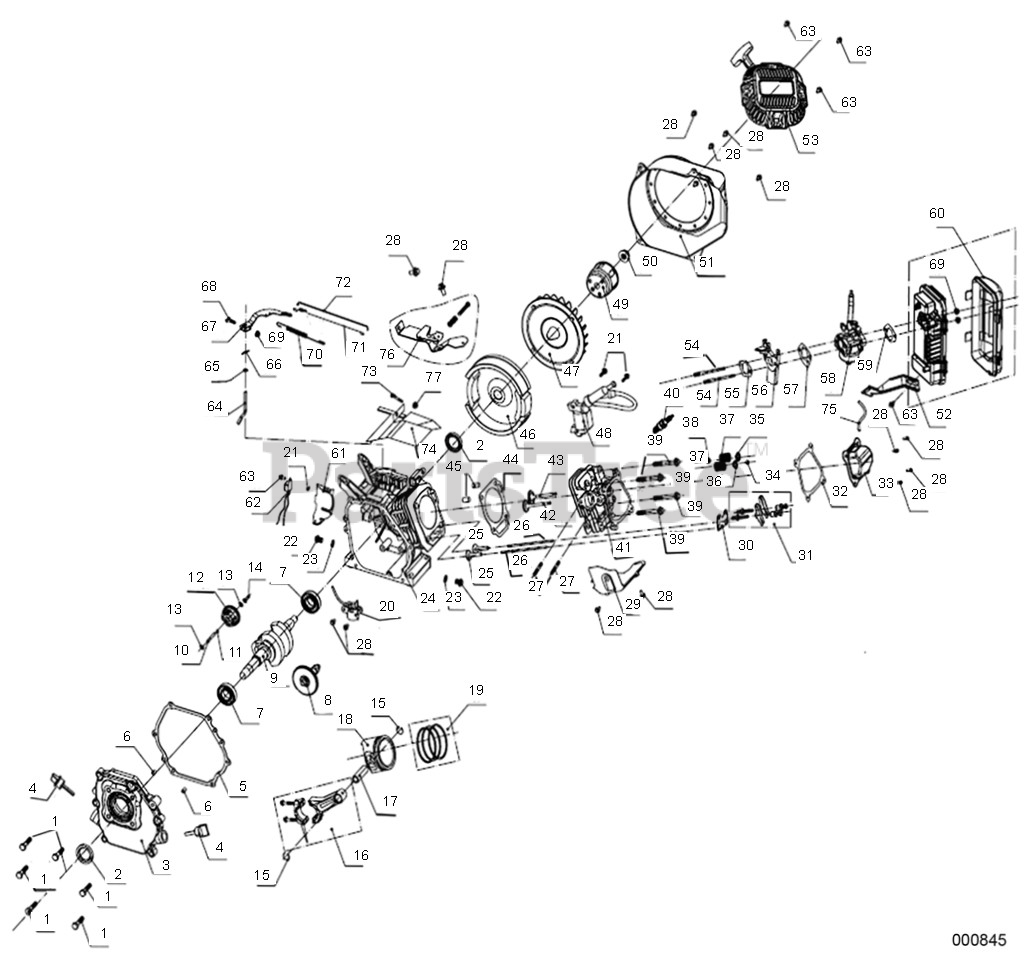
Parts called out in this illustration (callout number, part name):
1	BOLT (M8X33.5)
2	OIL SEAL (B2541)
3	CRANKCASE COVER
4	OIL DIPSTICK ASSEMBLY
5	CRANKCASE GASKET
6	DOWEL PIN (M8X14)
7	BEARING (6205)
8	CAMSHAFT ASSEMBLY
9	CRANKSHAFT ASSEMBLY
10	REGULATING SHAFT
11	SNAP RING
12	SPEED GOVERNING GEAR
13	GOVERNOR ARM SHAFT WASHER
14	GOVERNOR SPOOL
15	PISTON PIN CIRCLIP
16	CONNECTING ROD ASSEMBLY
17	PISTON PIN
19	PISTON RING SET
20	LOW OIL SENSOR
21	BOLT (M6X22)
22	OIL DRAIN BOLT (M10X15)
23	OIL DRAIN BOLT GASKET
24	CRANKCASE
25	VALVE TAPPET
27	STUD (M8X34)
28	BOLT (M6X12)
30	PUSH GUIDE ASSEMBLY
31	VALVE ROCKER ASSEMBLY
32	CYLINDER HEAD COVER GASKET
33	CYLINDER HEAD COVER
35	INTAKE SPRING SEAT
36	EXHAUST SPRING SEAT
37	VALVE SPRING
38	PIPE OIL SEAL
39	BOLT (M8X60)
40	SPARK PLUG
41	CYLINDER HEAD
42	EXHAUST VALVE
43	INTAKE VALVE
44	CYLINDER HEAD GASKET
45	DOWEL PIN (10X16)
47	FLYWHEEL FAN
48	IGNITION COIL
49	STARTING FLANGE
50	NUT (M14X1.5)
51	BLOWER HOUSING
52	AIR CLEANER BRAKE
53	RECOIL STARTER
54	STUD (M6X91)
55	INTAKE GASKET
56	CARBURETOR CUSHION BLOCK
57	CARBURETOR GASKET
58	CARBURETOR ASSEMBLY
59	AIR CLEANER GASKET
60	AIR CLEANER ASSEMBLY
62	OIL LEVEL SWITCH ASSEMBLY
63	BOLT (M6X8)
64	GOVERNOR ARM SHAFT
66	SPLIT PIN
67	REGULATING ARM
68	LOCK BOLT
70	BACK SPRING
71	REGULATING SPRING
72	REGULATING PULLING ROD
73	BOLT (M5X30)
74	CONTROL SHROUD
75	BREATHER TUBE
76	REGULATOR ASSEMBLY
